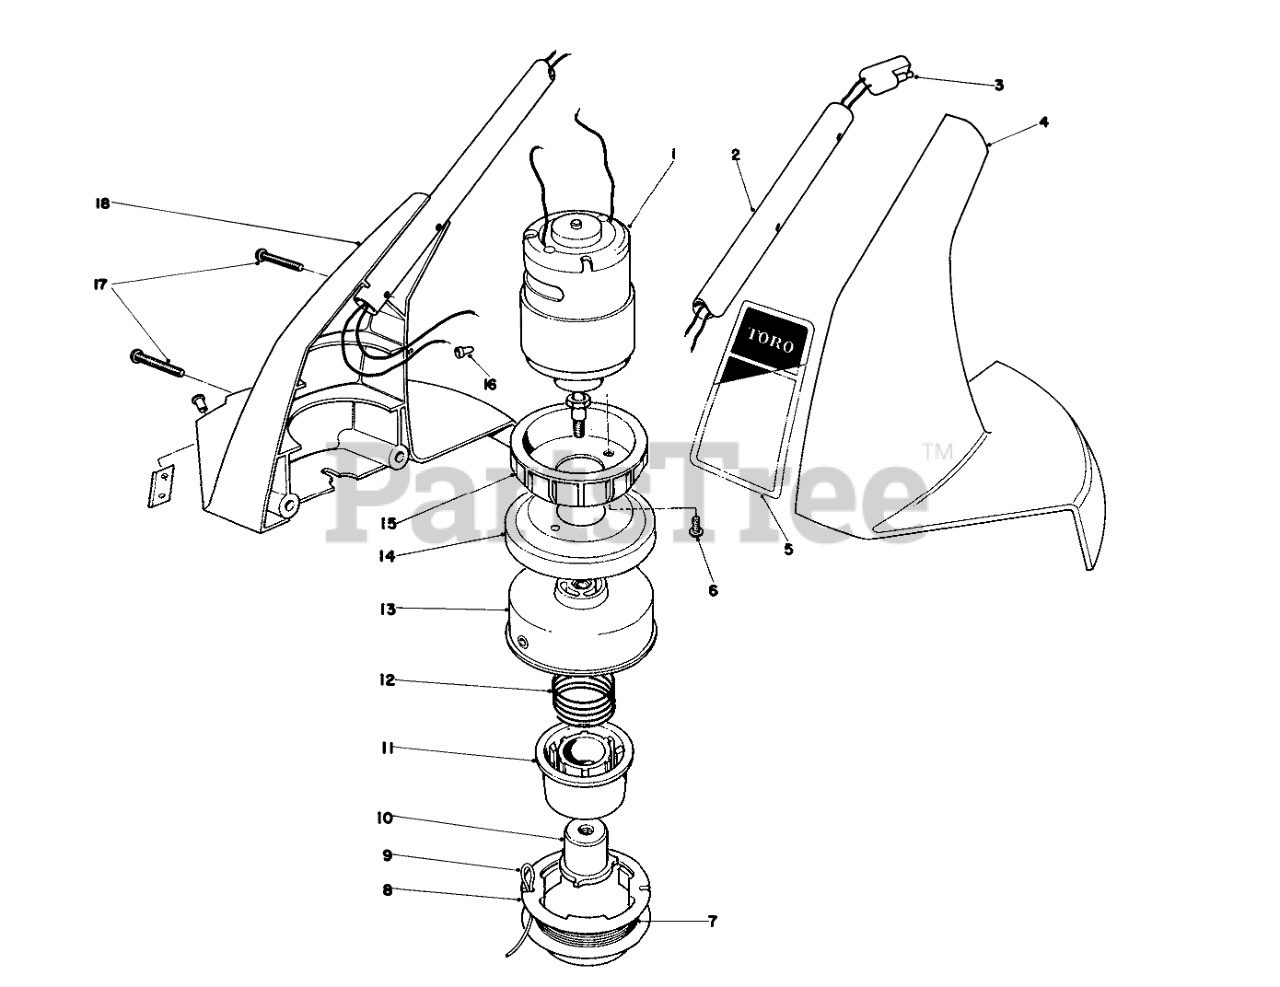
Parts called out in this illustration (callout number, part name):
1	Motor
2	EXTENSION HANDLE
3	WIRING HARNESS LOWER
4	Housing-L.H.
5	Decal-Housing
6	SCREW-PPH
7	50- .040" Line In Coil
8	SPOOL CAP
9	Prewound Spool
10	DRIVER
11	CORE - SPOOL
12	Spring
13	Drum w/Eyelet
14	DRUM CUP
15	Casting-Heat Sink
16	CONNECTOR WIRE JOINT
17	SCREW-PLASTITE
18	Right Motor Housing (Including Cut Off Blade)
